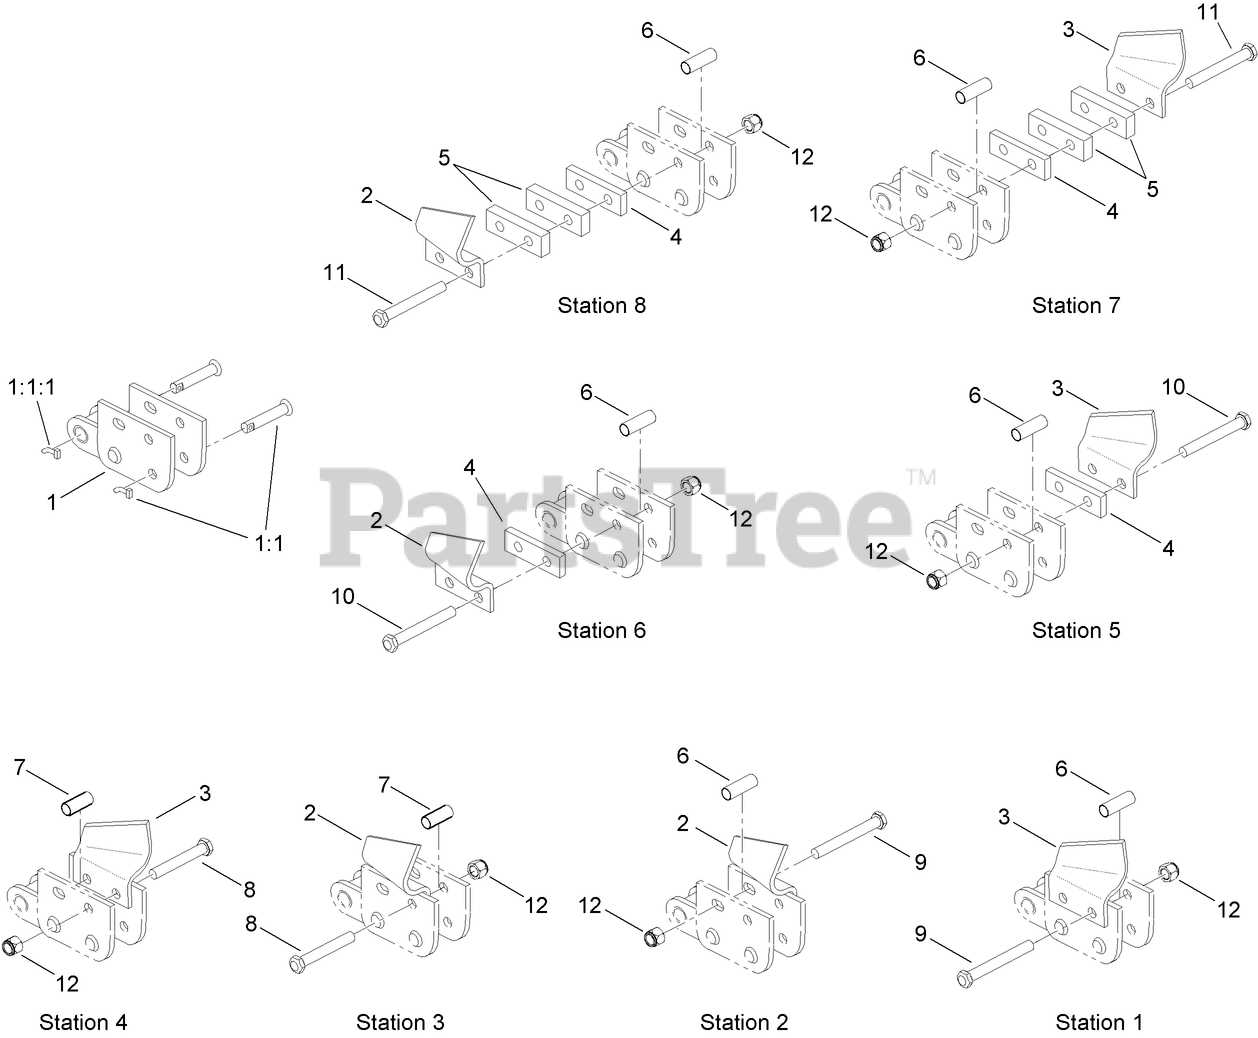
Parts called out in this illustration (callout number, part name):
1	CHAIN REPAIR LINK ASM
1:1	NOTCHED PIN AND KEEPER ASM
1:1:1	PIN-KEEPER
2	CUTTER-CUP, RH
3	CUTTER-CUP, LH
4	SPACER-FLAT
5	SPACER-FLAT
6	SPACER-TUBE, OUTSIDE MOUNT
7	SPACER-TUBE, INSIDE CUP
8	BOLT-HH
9	BOLT-HH
10	BOLT-HH
11	BOLT-HH
12	NUT-LOCK
